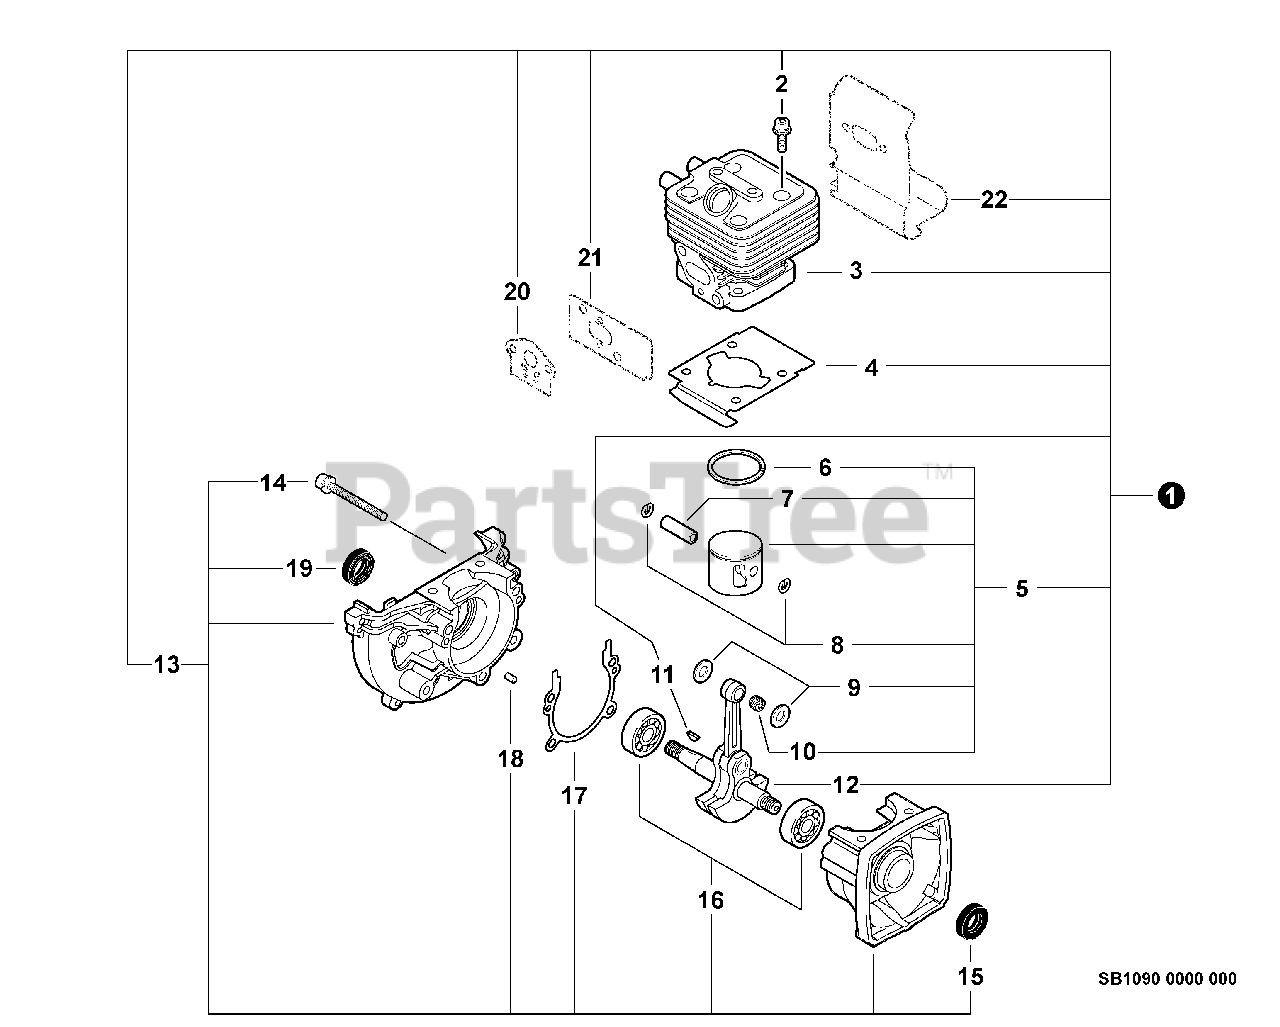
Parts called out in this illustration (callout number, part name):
1	SHORT BLOCK
2	BOLT 5×25
3	CYLINDER
4	GASKET, CYLINDER
5	PISTON KIT
6	RING, PISTON
7	PIN, PISTON
8	RING, SNAP
9	WASHER, THRUST
10	BEARING, NEEDLE 9
11	KEY, WOODRUFF
12	CRANKSHAFT ASSY
13	CRANKCASE KIT
14	BOLT 5×28
15	SEAL, OIL 12
16	BEARING, BALL - 6201 C3
17	GASKET, CRANKCASE
18	PIN, LOCATING 4
19	SEAL, OIL 12
20	GASKET, INTAKE
21	GASKET, INTAKE
22	SHIELD, EXHAUST
